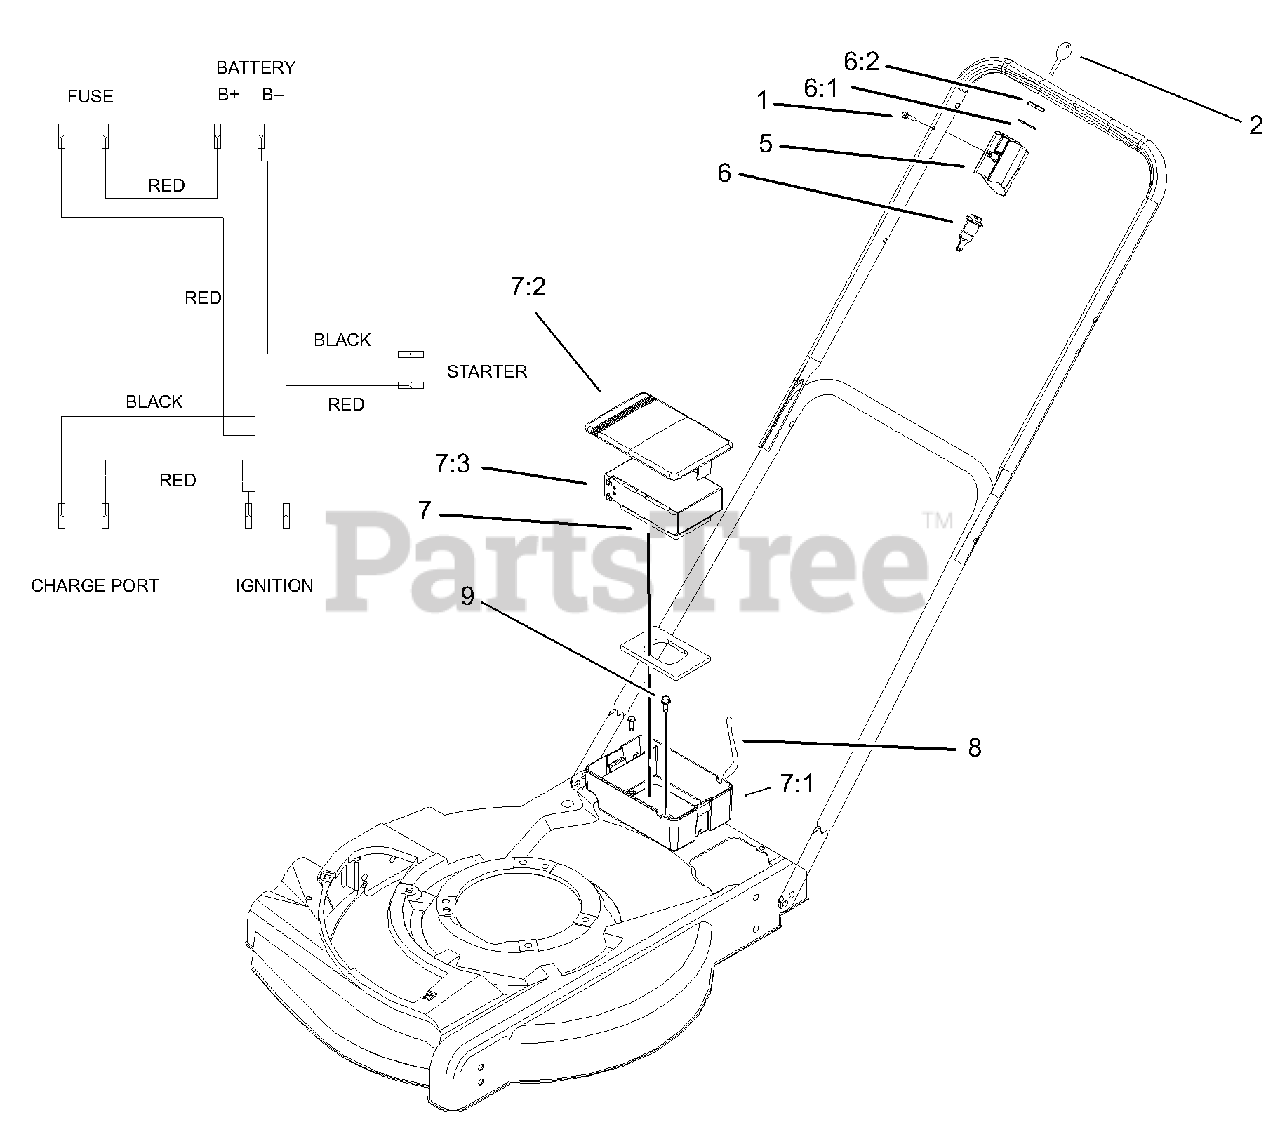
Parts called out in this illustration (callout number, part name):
2	Key-Ignition
5	Mount-Switch
6	Switch-Starter
6:1	Washer-Tooth
7	Battery ASM-Panasonic
7:1	Box-Battery
7:2	Cover-Battery
7:3	Battery-Panasonic, 12v
8	Harness-Wire
9	Screw-Tek
